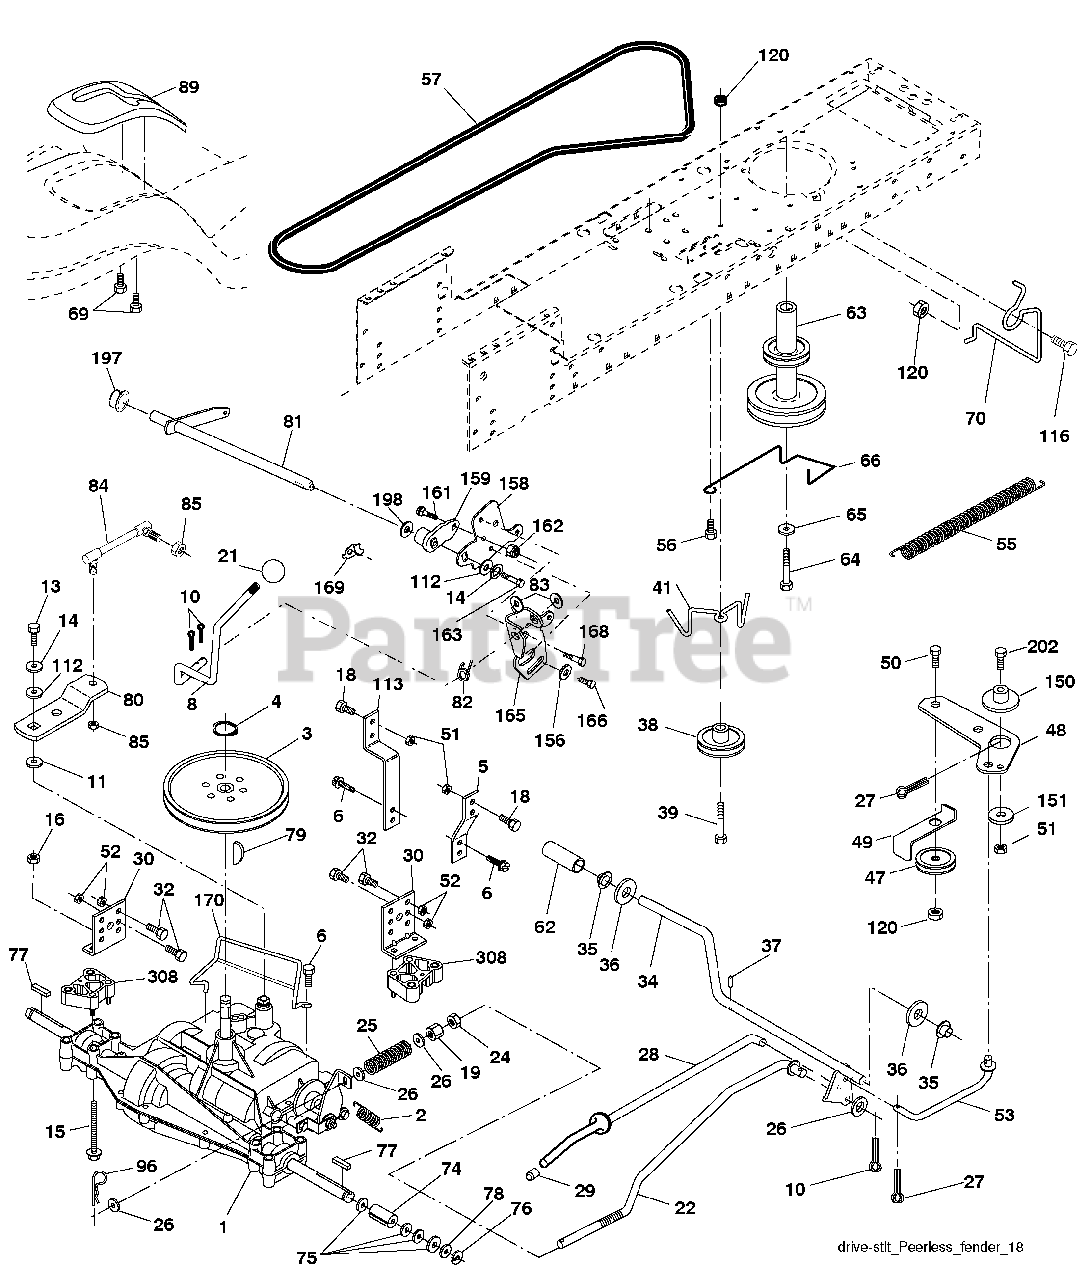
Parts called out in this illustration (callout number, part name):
2	Spring Return Brake T/a Zinc
3	Pulley Transaxle 18" Tires
4	Ring Retainer # 5100-62
5	Strap Torque 30 Degrees
6	Screw 5/16-18 x 3/4
8	Rod Shift Fender Adjust Lt
10	Pin Cotter 1/8 x 1 Cad
11	Washer Plate Shf 388 Sq Hole
13	Bolt 1/4-28 unf Gr. 8 w/Patch
14	Washer Lock Hvy Helical
15	Bolt Hex FLGHD 5/16-18 x 3.75
16	Nut Lock Hex w/ins 5/16-18
18	Bolt, Fin Hex 3/8-16 unc x 1 Gr. 5
19	Nut Lock 3/8-16 unc
21	Knob
22	Rod Brake
24	Nut Hex Jam 3/8-16 unc
25	Spring Rod Brake 2 00 Zinc
26	Washer 13/32 x 13/16 x 16 Ga.
27	Pin Cotter 1/8 x 3/4 Cad
28	Rod Brake Parking LT/YT
29	Cap Brake Parking
30	Bracket Mtg Transaxle
32	Bolt Hex Hd 5/16-18 unc x 3/4
34	Shaft Asm Pedal Foot
35	Bearing Nylon Blk 629 Id
36	Washer 21/32 x 1 x 16 Ga.
37	Pin Roll 3/16 x 1"
38	Pulley Composite Flat
39	Bolt RDHD 3/8-16 unc x 2-3/4 Gr. 5
41	Keeper Belt Flat Idler
47	Pulley Idler V Groove Plastic
48	Bellcrank Asm
49	Retainer Belt Style Spring
50	Bolt Carr. Sh. 3/8-16 x 1-1/2 Gr. 5
51	Nut Crownlock 3/8-16 unc
52	Nut Crownlock 5/16-18 unc
53	Link Clutch
55	Spring Return Clutch 6 75
56	Screw 3/8-16 x 1-1/4
57	V-Belt Ground Drive
62	Cover Pedal Blk Round
63	Engine Pulley
64	Bolt Hex
65	Washer Lock Hvy Hlcl Spr 7/16
66	Keeper Belt Engine Foolproof
69	Screw Hex wsh HiLo 1/4 x 1/2 unc
70	Guide Belt Mower Drive RH
74	Spacer Axle
75	Washer 25/32 x 1 1/4 x 16 Ga.
76	E-ring #5133-75
77	Key Square 2 0 x 1845/ 1865
78	Washer 25/32 x 1-5/8 x 16 Ga.
79	Key Woodruff #9 3/16 x 3/4
80	Arm Shift
81	Shaft Asm Cross Tapered PMST/20
82	Spring Torsion T/a
83	Washer 17/32 x 3/4 x 16 Ga.
84	Link Transaxle
85	Nut Lock Center 1/4 - 28 FNTHD
89	Console Shift STLT
96	Retainer Spring 1"
112	Washer 9/32 x 3/4 x 10 Ga.
113	Strap Torque LT
116	Bolt Rdhd Sq Neck 3/8-16 x 1
120	Nut Lock Flg. 3/8-16 unc
150	Spacer Retainer
151	Washer 13/32 x 2 x 10
156	Washer Srrted 5/16ID x 1.125
158	Bracket Shift Mount
159	Hub Tapered Flange Shift Lt
161	Bolt Rdhd Sqnk 1/4-20 x 3/4
162	Nut Crownlock 1/4-20 unc
163	Bolt Hex Fin 1/4-20 unc x 1 Gr. 5
165	Bracket Pivot Lever
166	Screw 5/16-18 x 5/8
168	Bolt Shoulder 5/16-18 x .561
169	Plate Fastening
170	Keeper Belt Transaxle Gear
197	Nyliner Snap-In
198	Washer Nyliner
202	Bolt RdHd 3/8-16 unc x 1-3/4 Gr. 5
308	Spacer Transaxle
